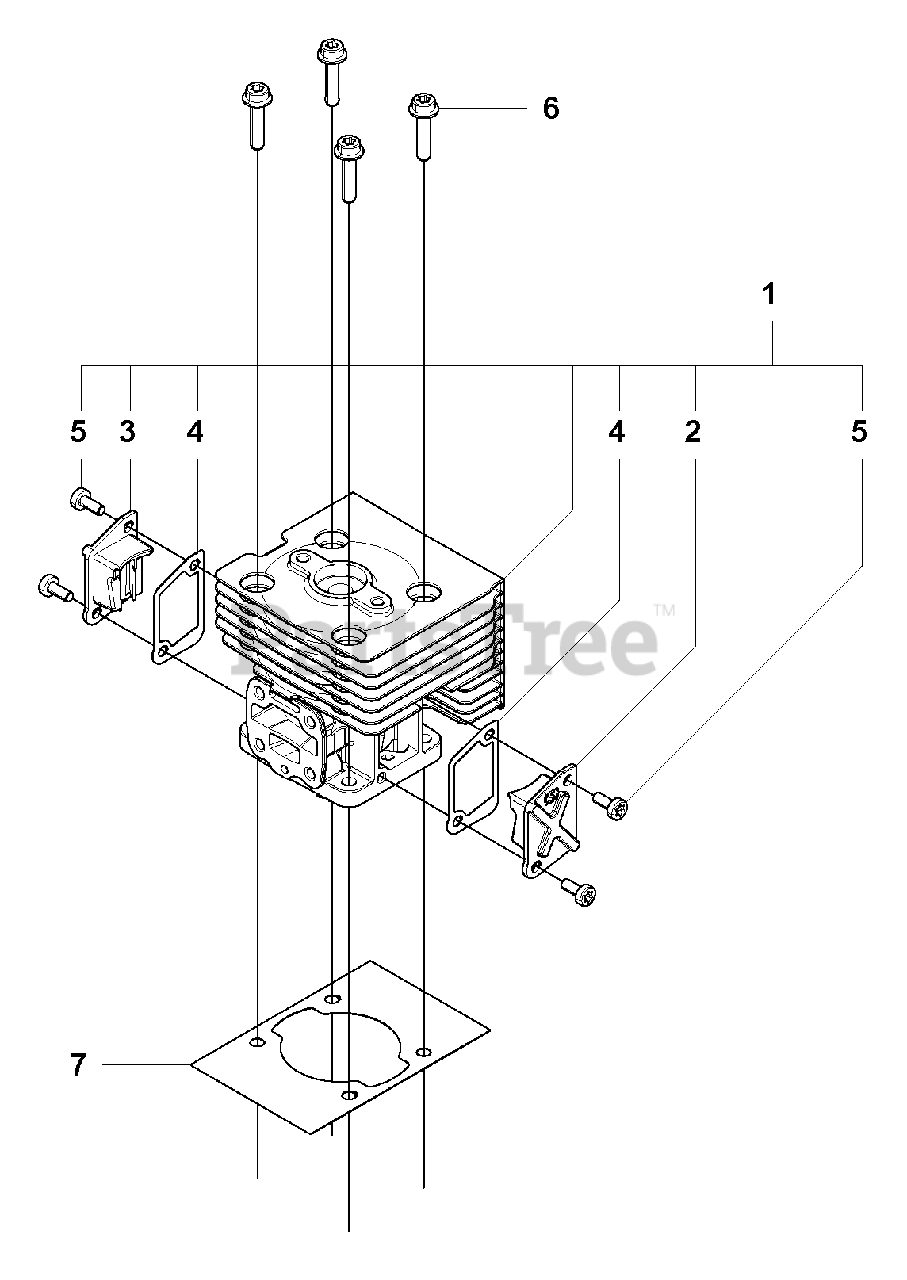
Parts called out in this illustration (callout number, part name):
1	CYLINDER
3	COVER TR (F)
6	BOLT
7	GASKET BASE
